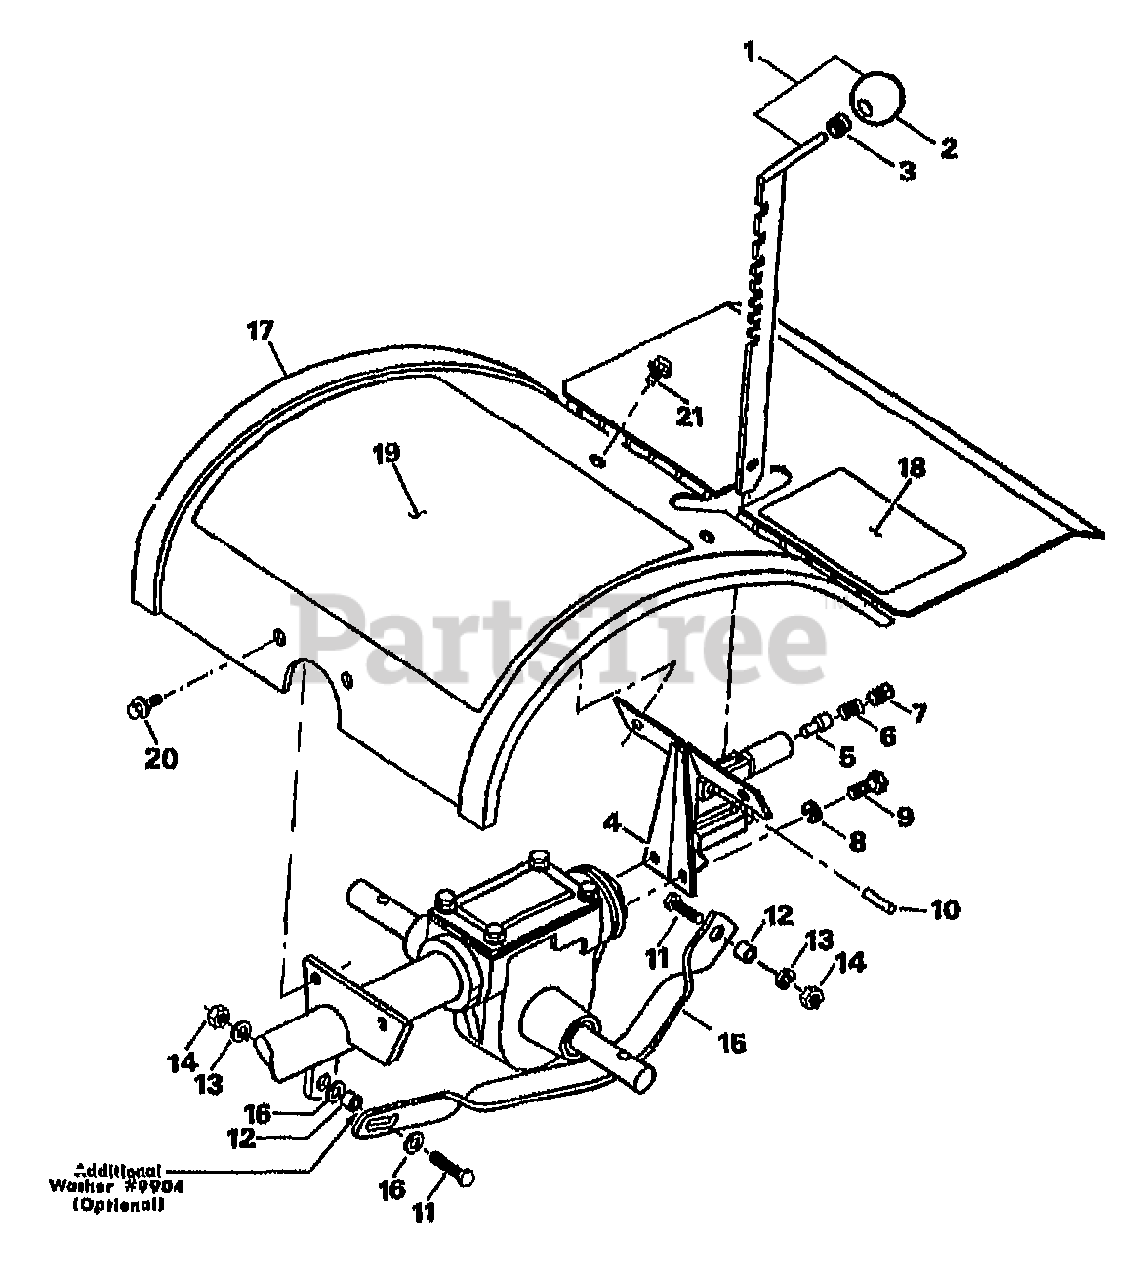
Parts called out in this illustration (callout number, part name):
1	DEPTH REGULATOR W/KNOB (Inc. 2 & 3)
2	KNOB-CONTROL
3	RING-TOLERANCE .5325 ID
4	ASSM-REAR HOOD BRKT - Depth Reg. & Tiller Hood (Inc. 10)
5	PLUNGER - Depth Reg. Locking
6	SPRING .406 X 1.25
7	PLUG-PIPE 1/4 NPT
8	WASHER-LK .312 ZP
9	SCR-HHC 5/16-18X.75 GR 5 ZP
10	PIN-SPIROL .188 X .875
11	SCR-HH 3/8-16X1.25
12	BUSHING-.5X.375X.3
13	WASHER-LK .375 @ DEPL
14	NUT-HEX 3/8-16 ZP
15	BAR-DRAG
16	WASHER-FLAT 3/8 SAE
17	ASSM-HOOD W/DECALS (Inc. 18-21)
18	DECAL-TB JR LOGO
19	DECAL-OPER INST (Operating Instructions)
20	SCR-HWH 5/16-18 X .5 STH
21	SCR-HWH 1/4-20 X .5 STH
